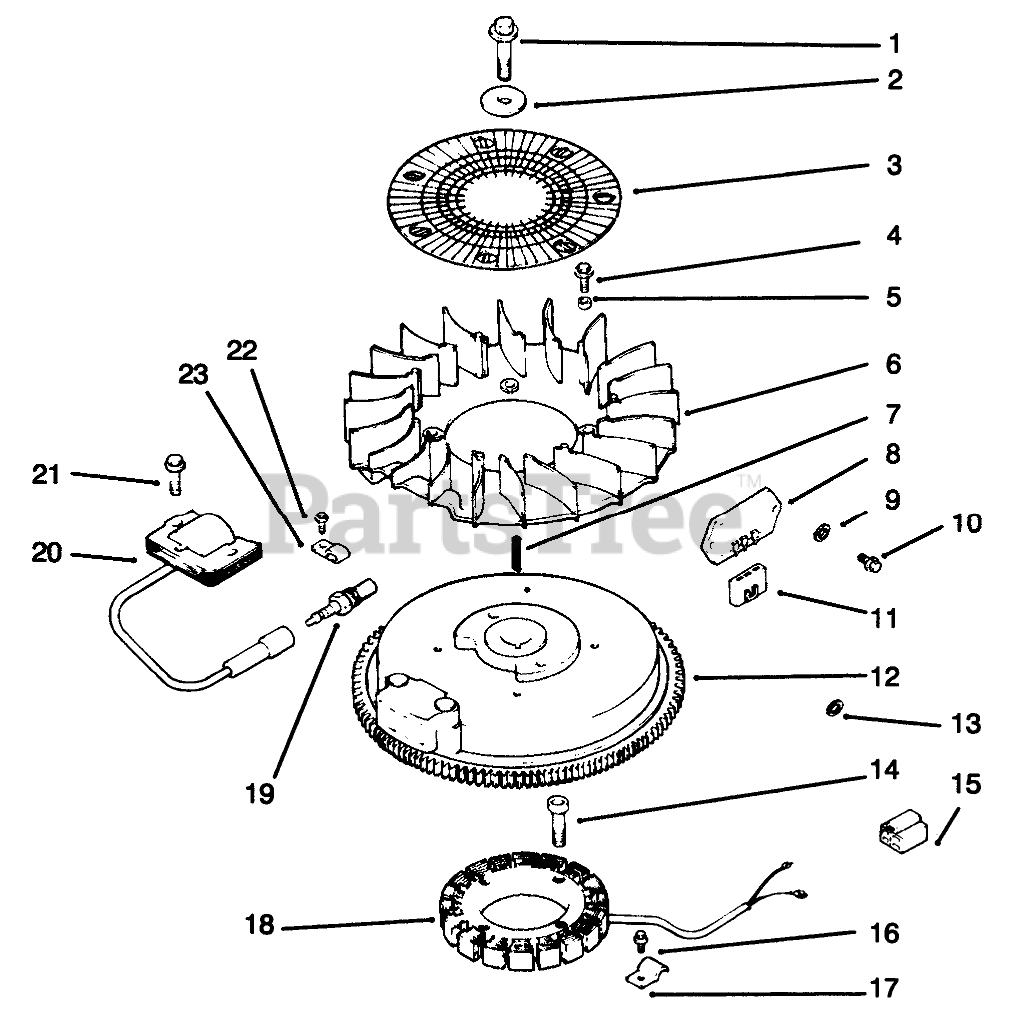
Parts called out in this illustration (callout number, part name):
1	Screw
2	Washer
3	Screen-Grass
4	Screw
5	Spacer
6	Fan
7	Key
8	Rectifier-regulator
9	Washer
10	Screw
11	Connector
12	Flywheel ASM
13	Washer
14	Screw
15	Connector
16	Screw
17	Clip-Stator Harness
18	Stator-15 Amp
19	Plug-Spark
20	Module-Ignition
21	Screw
22	Screw
23	Clip
